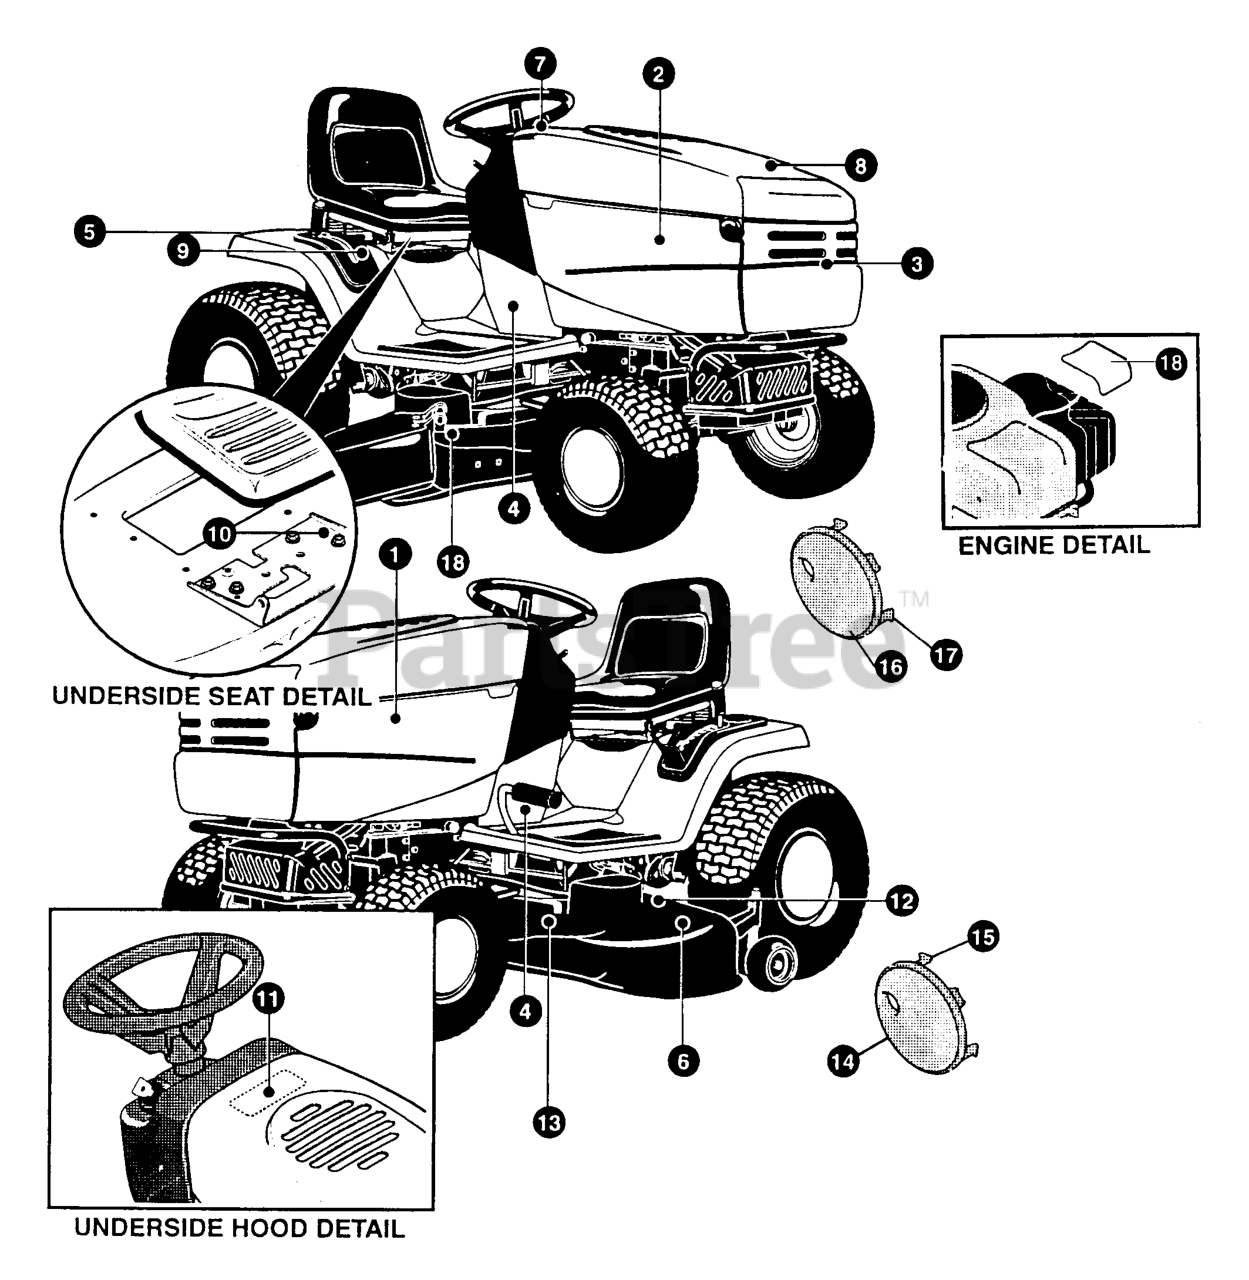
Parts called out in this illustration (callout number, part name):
1	DECAL, LH HOOD 17/42 SCOTTS
2	DECAL, RH HOOD 17/42 SCOTTS
3	DECAL, SCOTTS PIN STRIPE
4	DECAL, POW BY INTEK OIL FIL SYS
5	DECAL, SCOTTS S/D REAR
6	DECAL, CUTTING DECK
7	DECAL, CUST. CARE CENTER 406946
8	DECAL, EMBLEM HOOD SCOTTS
9	DECAL, 6-SPEED SCOTTS
10	REFERENCE ONLY
11	DECAL, MAINTENANCE B&S
12	DECAL, DECK LEVEL PROCEDURES
13	DECAL, DECK ROUTING 42"
14	HUBCAP 8"
15	CLIP, HUBCAP TINN #C25467-017-4
16	HUBCAP, 6"
17	CLIP, HUBCAP TINN #C25467-017-4
18	DECAL, ENGINE
